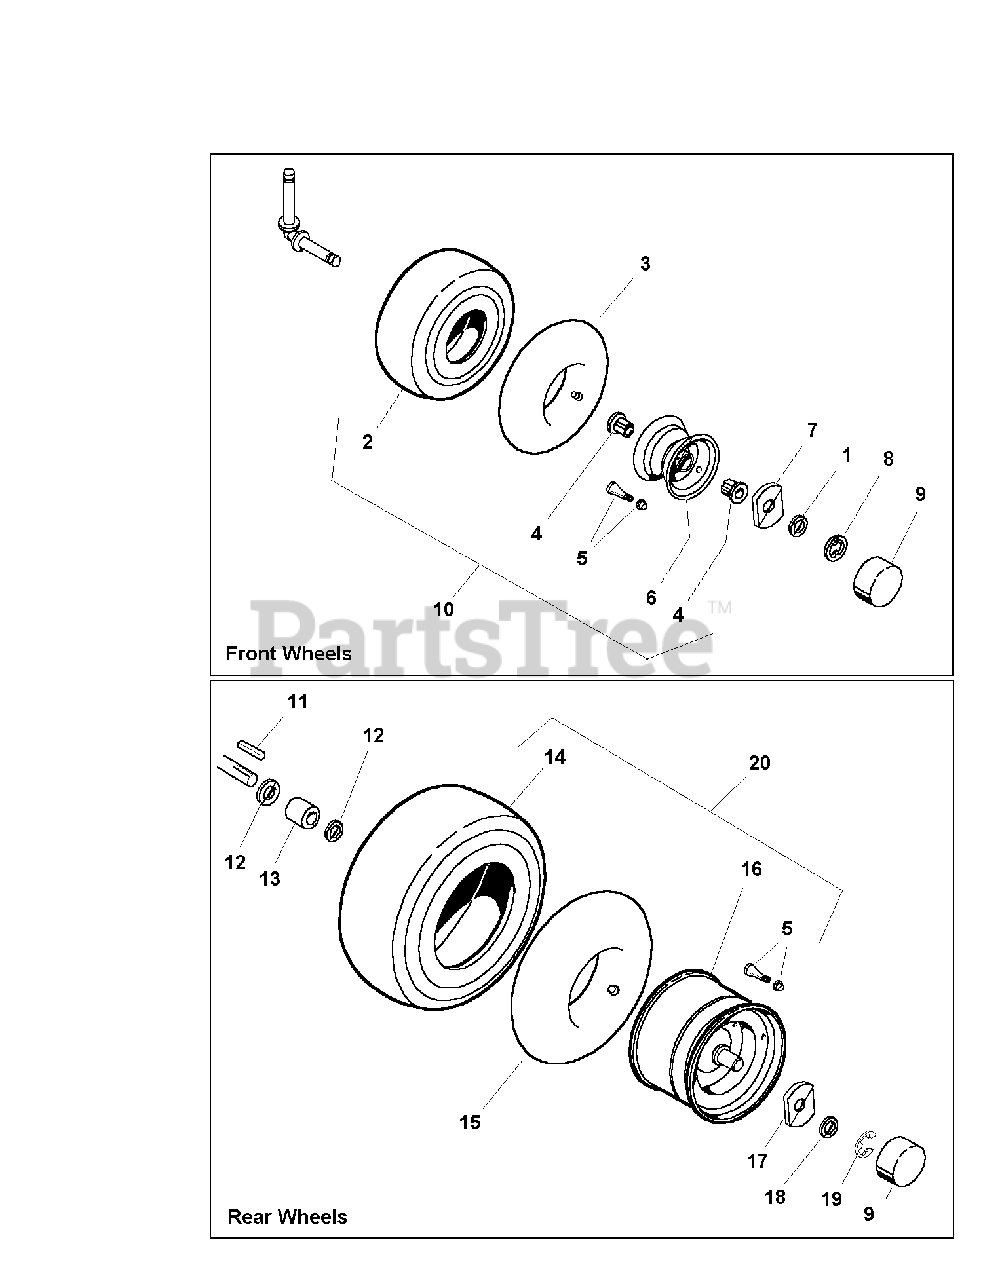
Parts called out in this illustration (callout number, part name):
1	WASHER
2	TIRE, 15 X 6.00, Super Turf
3	TUBE, 4.10/3.50 - 6
5	VALVE STEM & CAP ASSEMBLY
6	WHEEL, 4.50 X 6.00, (Includes Ref. No. 4)
7	WASHER, Special
8	RING, Retainer
10	WHEEL & TIRE ASSEMBLY, (Includes Ref. Nos. 2, 4, 5 & 6)
11	KEY
14	TIRE, 20 X 10.00 Super Turf
15	TUBE, 20 X 8.00 - 10
16	WHEEL, 7.00 x 7.96
17	WASHER, Special
18	WASHER
19	RING, E Retaining
20	WHEEL & TIRE ASSEMBLY, (Includes Ref. Nos. 5, 14 & 16)
